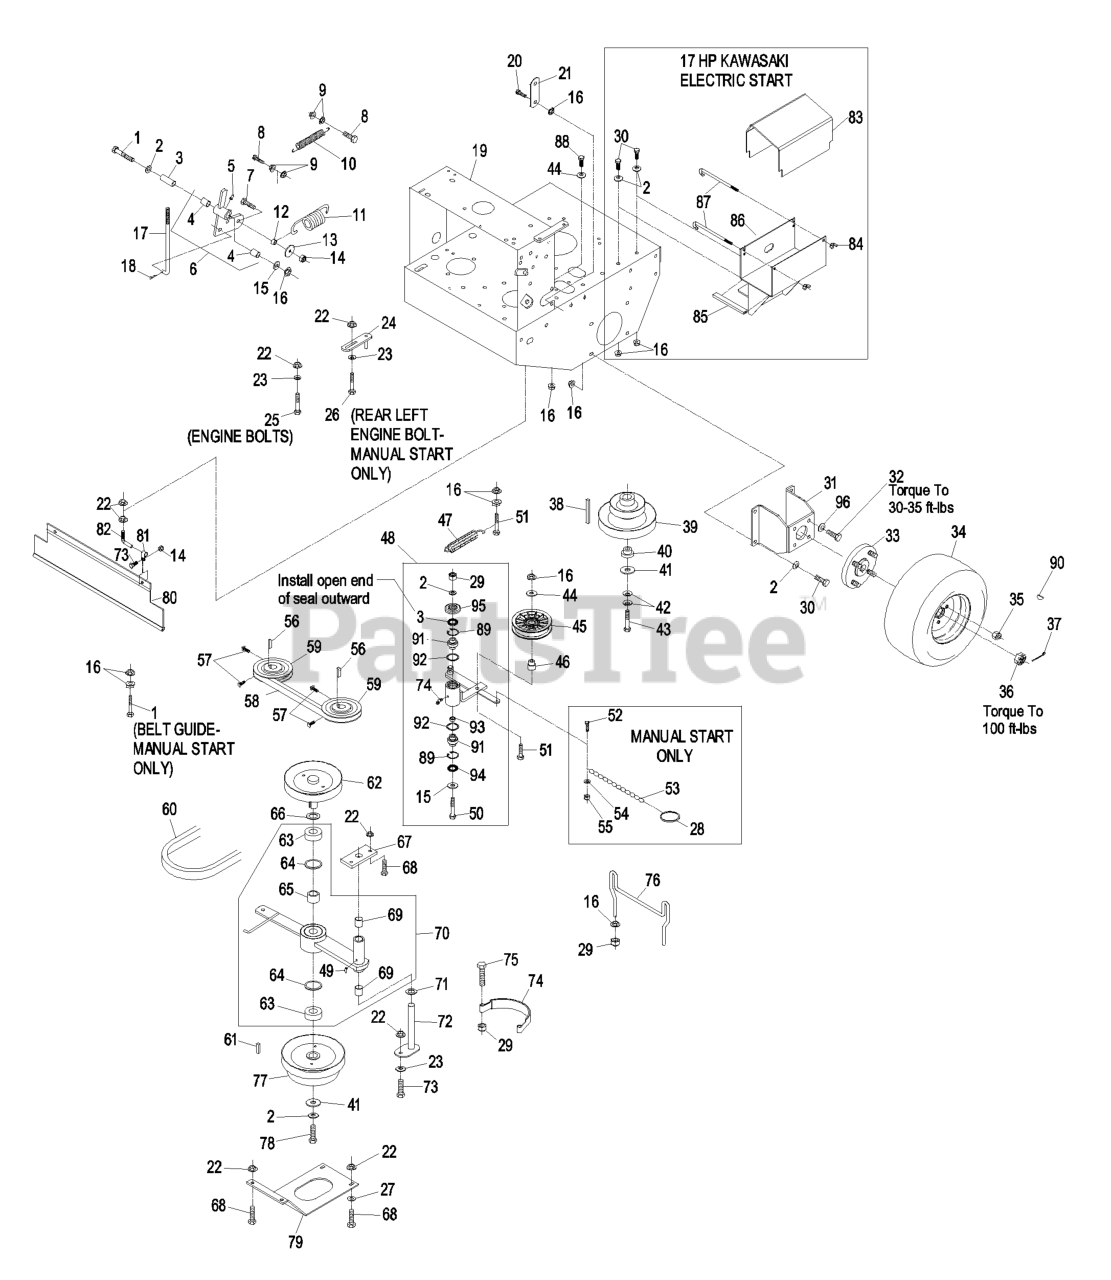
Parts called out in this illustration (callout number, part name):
1	SCREW-HH
2	WASHER-BELLEVILLE
3	SEAL-LIP, SINGLE
4	SLEEVE-BEARING
5	FITTING-GREASE
6	ASM,PIVOT W/BUSHINGS
7	SCREW-HH
8	SCREW-HH
10	SPRING,EXTENSION
11	SPRING,EXTENSION
12	SPACER,CLUTCH ANCHOR
14	NUT-LOCK, NI
15	WASHER-FLAT
16	NUT-HHF, WHIZ
17	LINKAGE,LOWER
18	PIN-COTTER
19	KIT,TTHP ENG DECK
20	SCREW-HH
21	ARM-LIFT, DECK
23	WASHER-SPRING
24	GUIDE-BELT
25	SCREW-HH
26	SCREW-HH
27	WASHER-FLAT
28	RING-SPLIT
29	NUT-LOCK, NI
30	SCREW-HH
31	WLD,MOTOR MOUNT 36
32	SCREW-HH
34	WHEEL AND TIRE ASM
35	NUT-LUG
36	NUT-HEX, SLOTTED
37	PIN-COTTER
38	KEY,MACH 1/4X1/4X2-5/8
39	SHEAVE, DRIVE
40	BUSHING,CLUTCH KEEPER
42	WASHER-SPRING
43	SCREW-HH
44	WASHER-FLAT
45	PULLEY-IDLER, FLAT
46	BUSHING-IDLER
48	KIT,PUMP IDLER ARM TTHP
49	FITTING-GREASE
50	SCREW-HH
51	SCREW-HH
52	SCREW-HSH
53	CHAIN-LINK, TWIST
54	WASHER-FLAT
55	NUT-LOCK, NI
57	SCREW-SET
58	BELT,COG A 50.55
59	SHEAVE ASM
60	BELT,B-38.0
62	SHEAVE, W/ SHAFT
63	BEARING,CLUTCH SHAFT
64	RING-SNAP
65	SPACER,CLUTCH BEARING
66	WASHER-SPACER
67	PLATE-CLUTCH PIVOT
68	SCREW-HH
69	SLEEVE,BEARING
70	ASM,CLUTCH ARM W/BEARING
71	WASHER-SPACER
72	WLD,PIN PIVOT
73	SCREW-HH
74	BAND,BRAKE BLADE
75	SCREW-HH
76	GUIDE,BELT (PLTD)
77	SHEAVE,6.13 W/HUB
78	SCRW,CAP HH
79	PLATE-GUARD
80	SHIELD-DRAG
81	CLIP-LOOM
82	MOUNT,DRAG SHIELD
83	COVER,BATTERY W/DECAL
84	WINGNUT
85	TRIM-LOK
86	ASM,BATTERY STAND W/TRIM
87	BOLT - HOLD DOWN
88	SCREW-HH
89	RING-SNAP
90	KEY-WOODRUFF
91	BEARING-SPHERICAL
94	SEAL-LIP, DOUBLE
95	GUARD-TOP
96	Washer, Spring Disc
